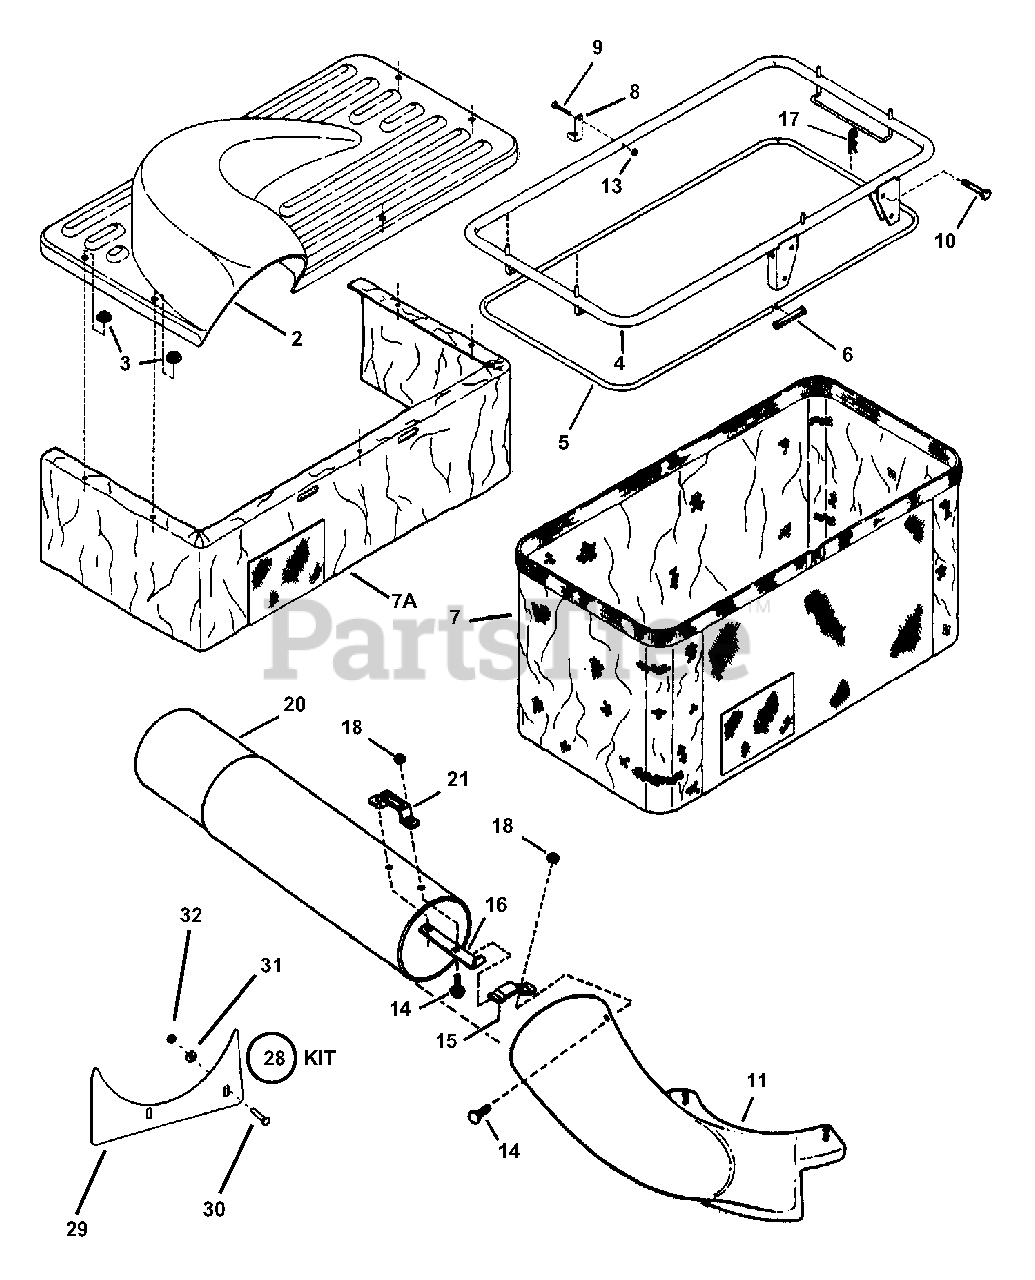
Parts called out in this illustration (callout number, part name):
2	TOP, Container
3	WASHER, Faceted
4	FRAME, Structure
5	ROD, Bag
6	CONNECTOR, Bag Rod
7	BAG, Grass
7A	SKIRT, Dust
8	LATCH, Top
9	SCREW, #10-32 Hex Head Cap, Grade 2
10	PIN, 5/16 x 1-11/16" Clevis
11	ADAPTER, 38" Deck
13	NUT, #10-32 Hex Nyloc
14	BOLT, 1/4-20 x 3/4" Short Neck Carriage, Grade 5
15	LATCH, Tube
16	BASE, Handle
17	PIN, 3/32 x 1-1/2" Hair
18	NUT, 1/4-20 Hex, Grade 5 or B
20	TUBE, Grass
21	HANDLE, Tube
28	KIT, Catcher, Debris Shield
29	SHIELD, Debris
30	BOLT, 1/4-20 x 1-1/2" Hex
31	WASHER, 1/4" Flat
32	NUT, 1/4-20 Hex top Lock
